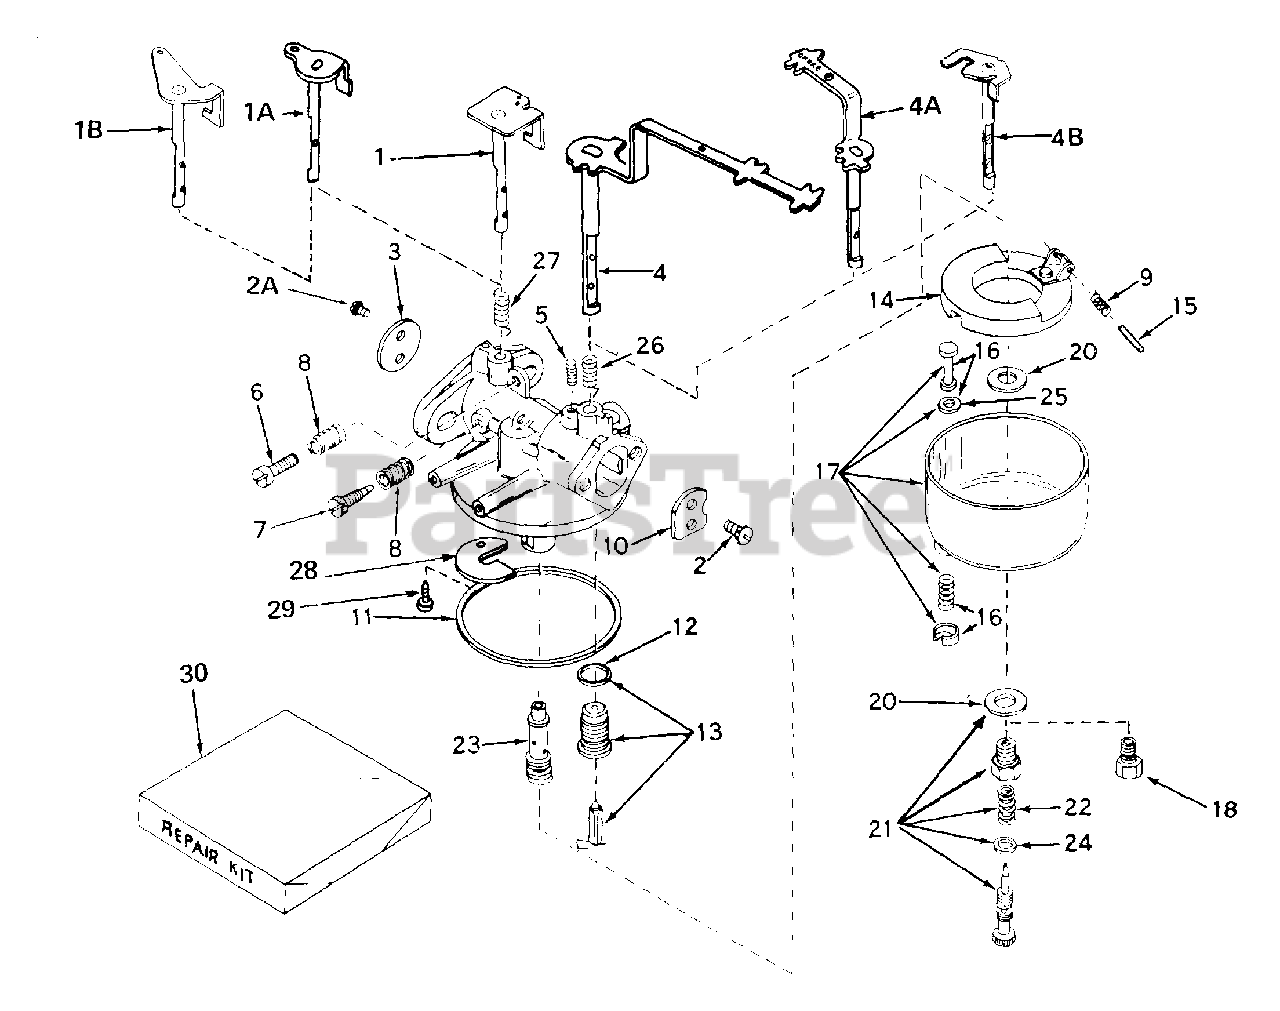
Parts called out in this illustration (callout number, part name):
1	"Shaft & Lever Assy., Throttle
2	Screw, Pan hd. Sems, 4-40 x 3/16
2A	Screw, Pan hd. Sems, 4-40 x 3/16
3	Shutter, Throttle
4	Shaft & Lever Assy., Choke
6	Screw, Throttle adjusting
7	Needle, Idle adjusting
8	Spring, Adjusting needle
9	Spring, Float shaft
10	Shutter, Choke
11	Gasket, Bowl-to-body
12	Gasket, Valve seat
13	Valve, Seat, Gasket & Spring Assy. (I ncl.
15	Shaft, Float
16	Drain Assy., Bowl (lncl. No. 25)
17	Bowl & Drain Assy.,(Incl. No. 16)
18	Float Bowl Nut
20	Gasket, Bowl-to-body
22	Spring, Adjusting needle
23	Nozzle, Main
25	Gasket, Drain stem
27	Spring, Throttle return
30	Repair Kit
